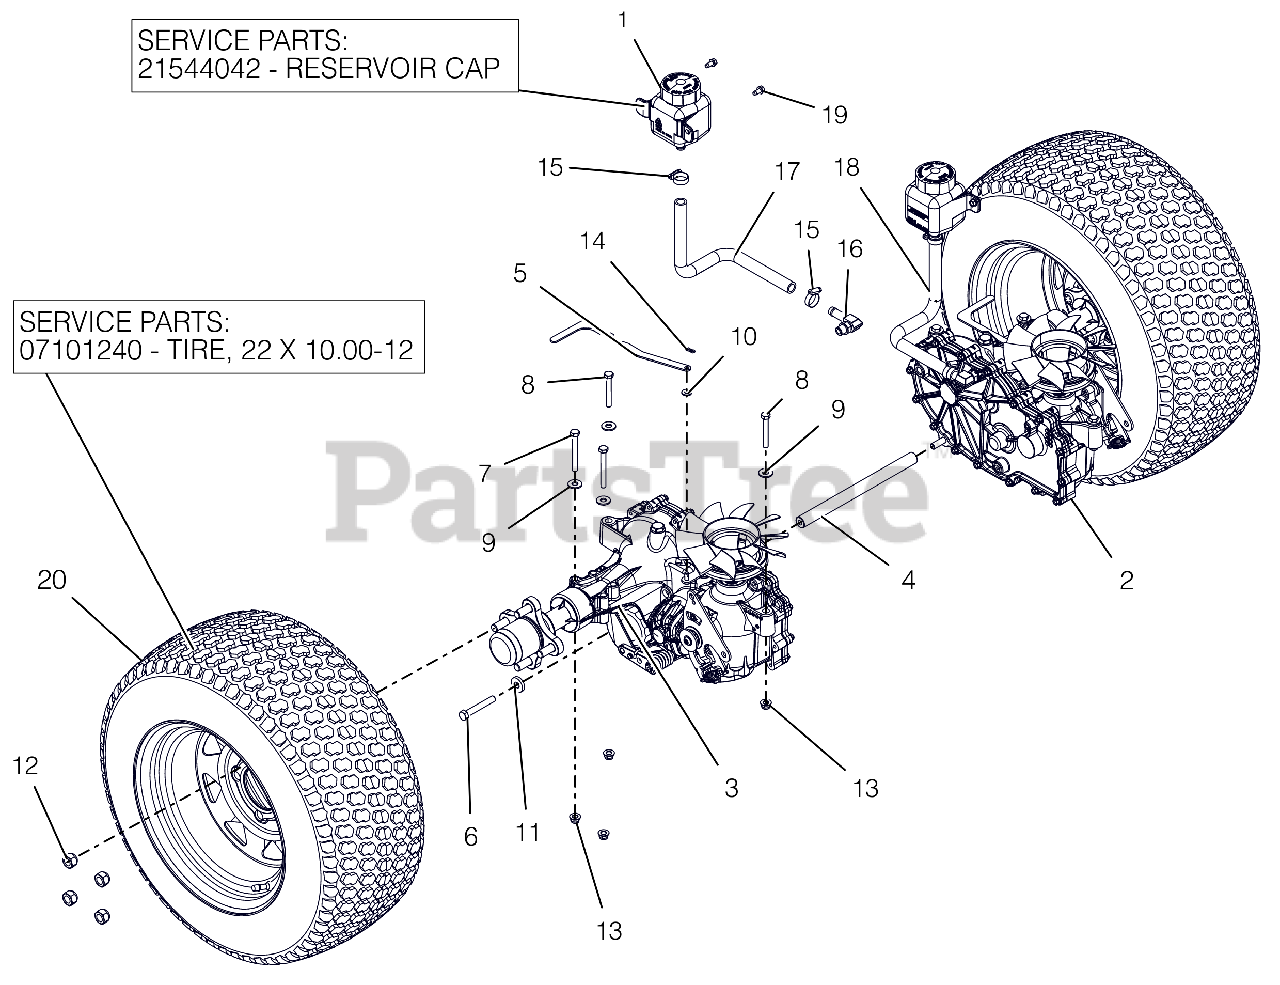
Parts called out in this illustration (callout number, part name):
1	TANK, EXPANSION
1	CAP, HYDRO RESERVOIR REPLAC.
2	TRANSAXLE, ZT3100 LH
3	TRANSAXLE, ZT3100 RH
4	SHAFT, TRANSAXLE SUPPORT
5	BRKT, VALVE DUMP
6	@BLT-HEX .38-16X2.50 GR5 YWZC
7	@BLT-HEX .31-18X2.75 GR5 YWZC
8	@BLT-HEX .31-18X2.25 GR5 YWZC
9	@WSHR-FL-STL.38X.875X.083 YWZC
10	@WSHR-FL-STL.281X.62X.065 YWZC
11	WSHR-FL-STL .406X1.00X.188 YWZ
12	WHEEL NUT .500-20 YZ
13	@NUT-LK-NYL-FLG .31-18 YWZC
14	PIN-HAIR, ENDRIES #25 YWZC
15	CLAMP,.88 DIA. HOSE
16	FITTING, HYD (90 DEG)
17	HOSE, FORMED EXPANSION -HD RH
18	HOSE, FORMED EXPANSION -HD LH
19	SCR-TAP .25-20X.50 HWH TR YWZ
20	ASM, WHL/TIRE 22X10.00-12 K500
20	TIRE, 22X10.00-12
